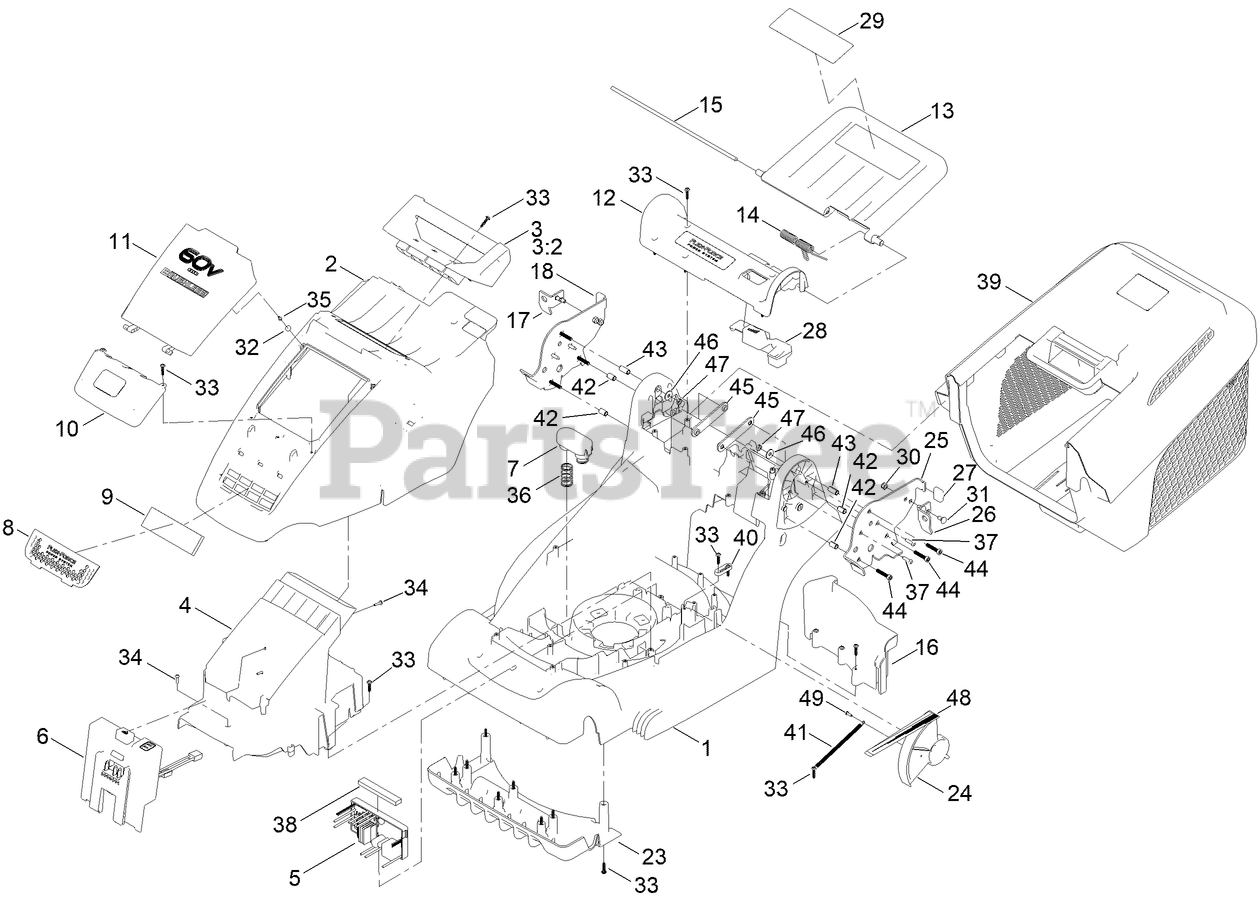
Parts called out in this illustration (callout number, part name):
2	TOP COVER
3	CARRY HANDLE ASM
3:2	ARTWORK - 43CM
4	BATTERY HOLDER
5	DRIVER-MOTOR, SELF PROPELLED
5	DRIVER-MOTOR, PUSH
6	BATTERY INTERFACE ASSEMBLY
7	BATTERY SPRING COVER
8	AIR INLET GRILL-TORO
9	Cover, Exhaust-Right
10	BATTERY DOOR LOWER, PRINTED
11	BATTERY DOOR, PRINTED
12	HOC COVER
13	REAR DEFLECTOR
14	SPRING, REAR DEFLECTOR
15	ROD, REAR FLAP
16	GRASS SHIELD (43)
17	BRACKET, V-STOW, RIGHT
18	MOUNT PLATE, HANDLEBAR, RIGHT
23	FRONT FINS
24	HOC DIAL, PRINTED
25	MOUNT PLATE, HANDLEBAR, LEFT
26	BRACKET, V-STOW, LEFT
27	RUBBER FOOT-V-STOW
28	HOC BUTTON
29	DECAL SAFETY 60V
30	NUT, NYLOC, M6X1
31	BOLT, CARRIAGE, M6X1
32	MAGNET
35	PT SCREW 3MM X 10MM CSK
36	SPRING, BATTERY EJECT
37	SCREW-TORX
38	FILTER, AIR-CONTROL BOARD
39	GRASS BOX ASM
41	SPRING
45	BRACE-BAR
46	WASHER
48	DECAL - HOC (TORO 43CM)
